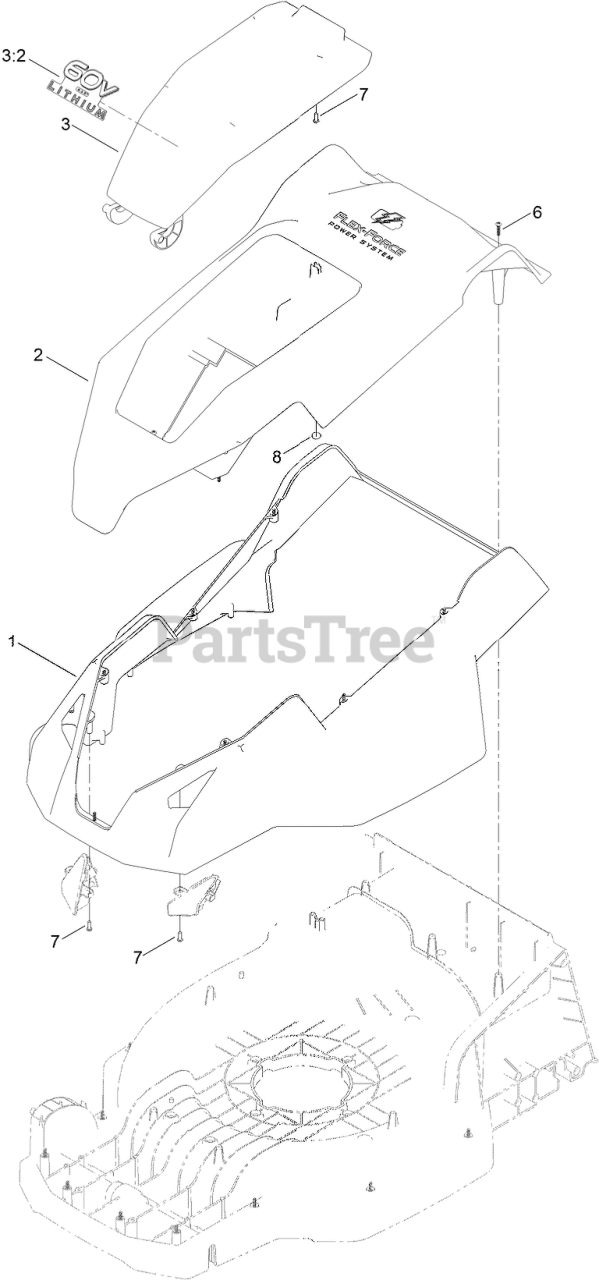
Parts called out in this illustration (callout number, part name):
1	SHROUD-BOTTOM, LED
2	SHROUD-TOP
3	ASM-COVER, BATTERY
3:2	DECAL-60V, LITHIUM
6	SCREW-PPH
7	SCREW
8	MAGNET-COVER
